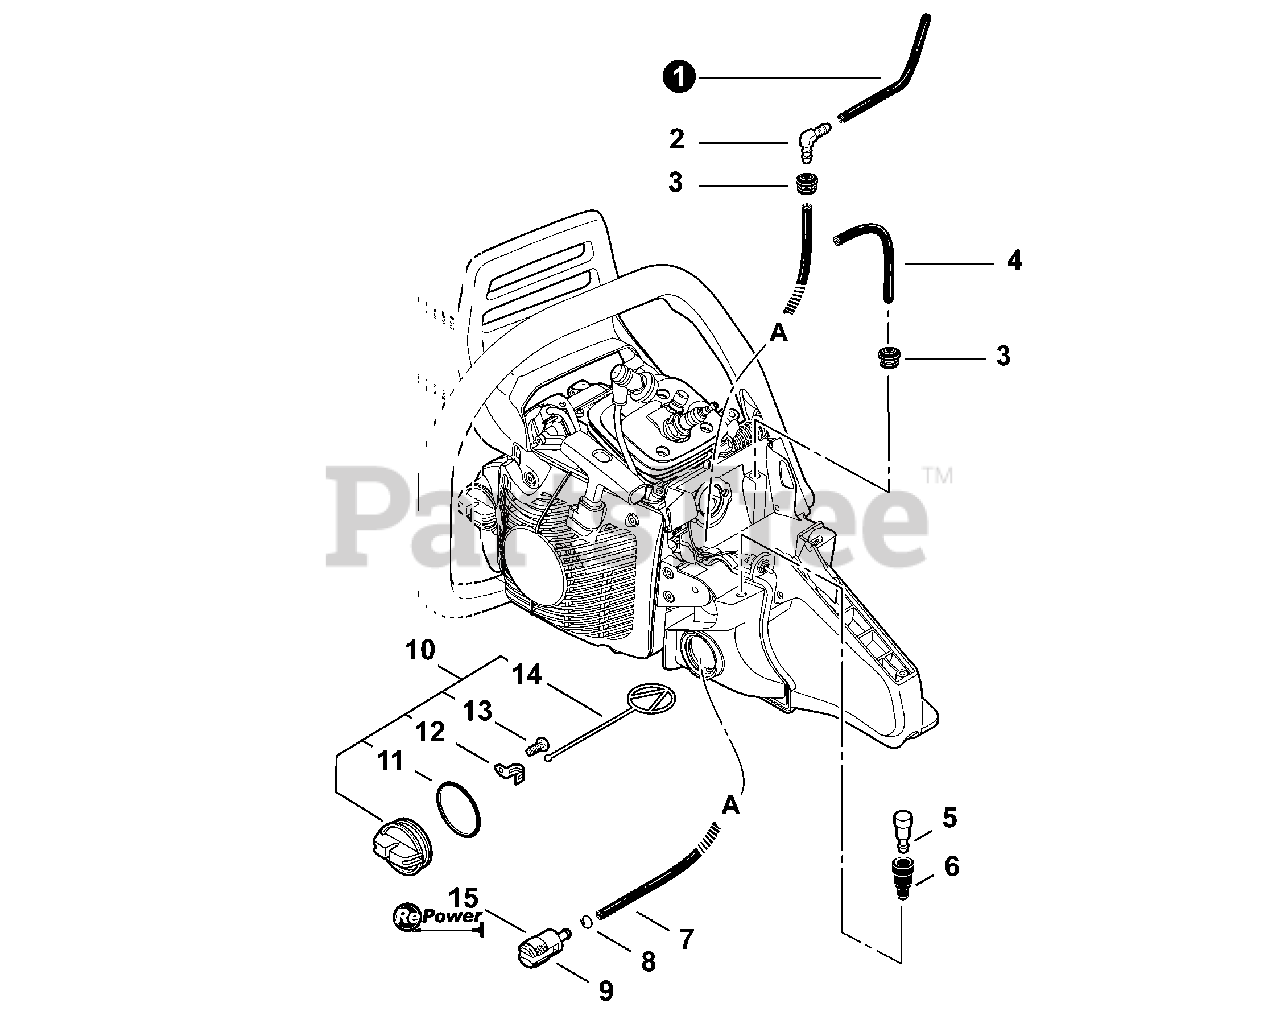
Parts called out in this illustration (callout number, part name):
1	PIPE, FUEL 3×6×135L
2	CONNECTOR, PIPE
3	GROMMET
4	PIPE, IMPULSE 3×6(8)×160
5	VENT ASSY
6	GROMMET, VENT
7	PIPE, FUEL 3×5×120 BLACK
8	CLIP Ø6
9	FILTER, FUEL
10	CAP ASSY, FUEL
11	O-RING 29
12	RETAINER, CONNECTOR
13	SCREW, TAPPING 3×8
14	CONNECTOR, CAP L= 60 MM
15	TUNE-UP KIT - REPOWER
